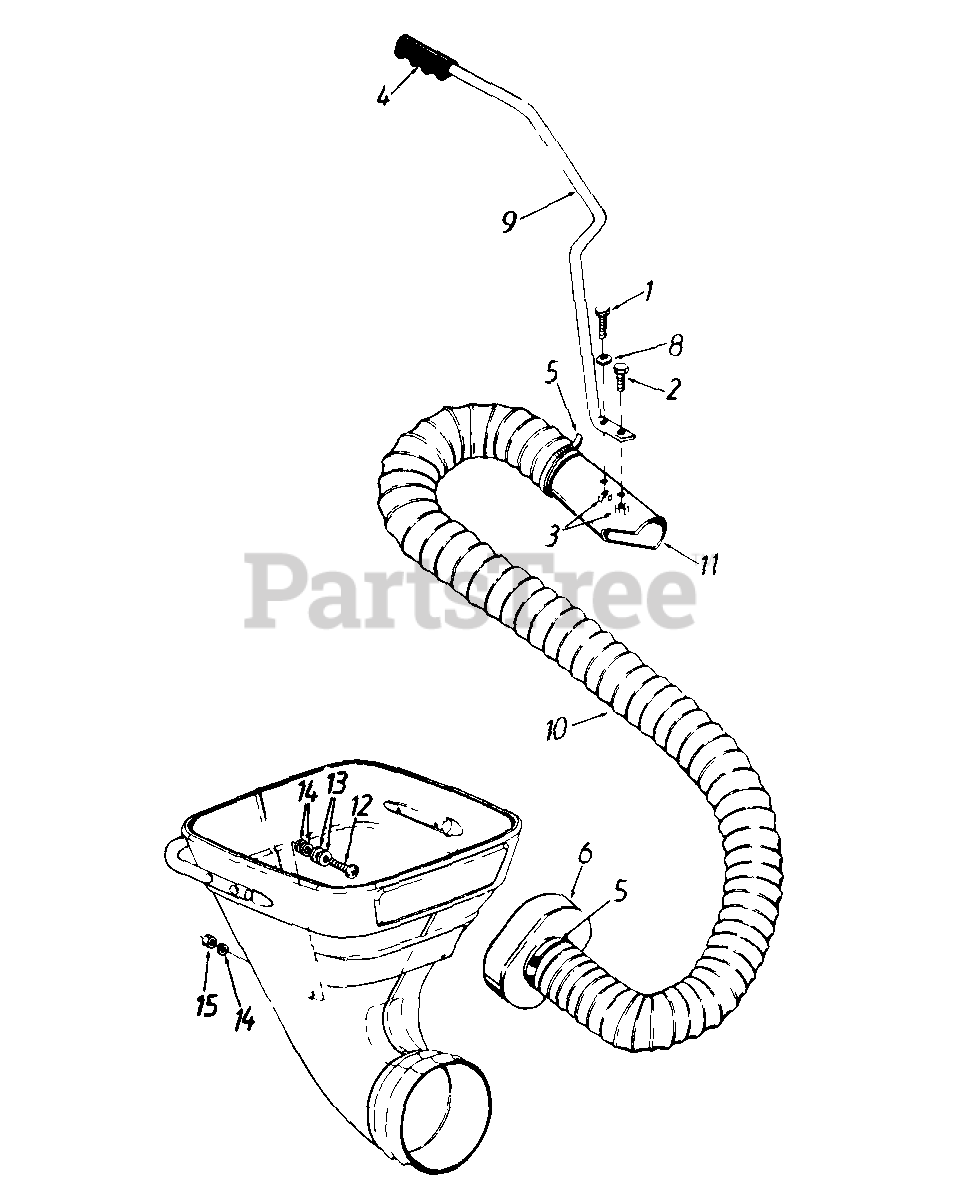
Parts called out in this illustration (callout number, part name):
1	Hex Bolt 1/4-20 x 1.25" Lg.
2	Hex Bolt 1/4-20 x .62" Lg.
3	Hex L-Nut 1/4-20 Thd.
5	Adj. Hose Clamp 5" Dia.
8	Saddle Washer .32" I.D. x .937"
10	Hose - 5" Dia.
11	Nozzle Tube
12	Truss Mach. Scr. 5/16-18 x 3/4" Lg.
13	Fl-Wash .344" I.D. x .75" O.D.
14	Fl-Wash .328" I.D. x .68" O.D.
15	Hex L-Nut 5/16-18 Thd.
